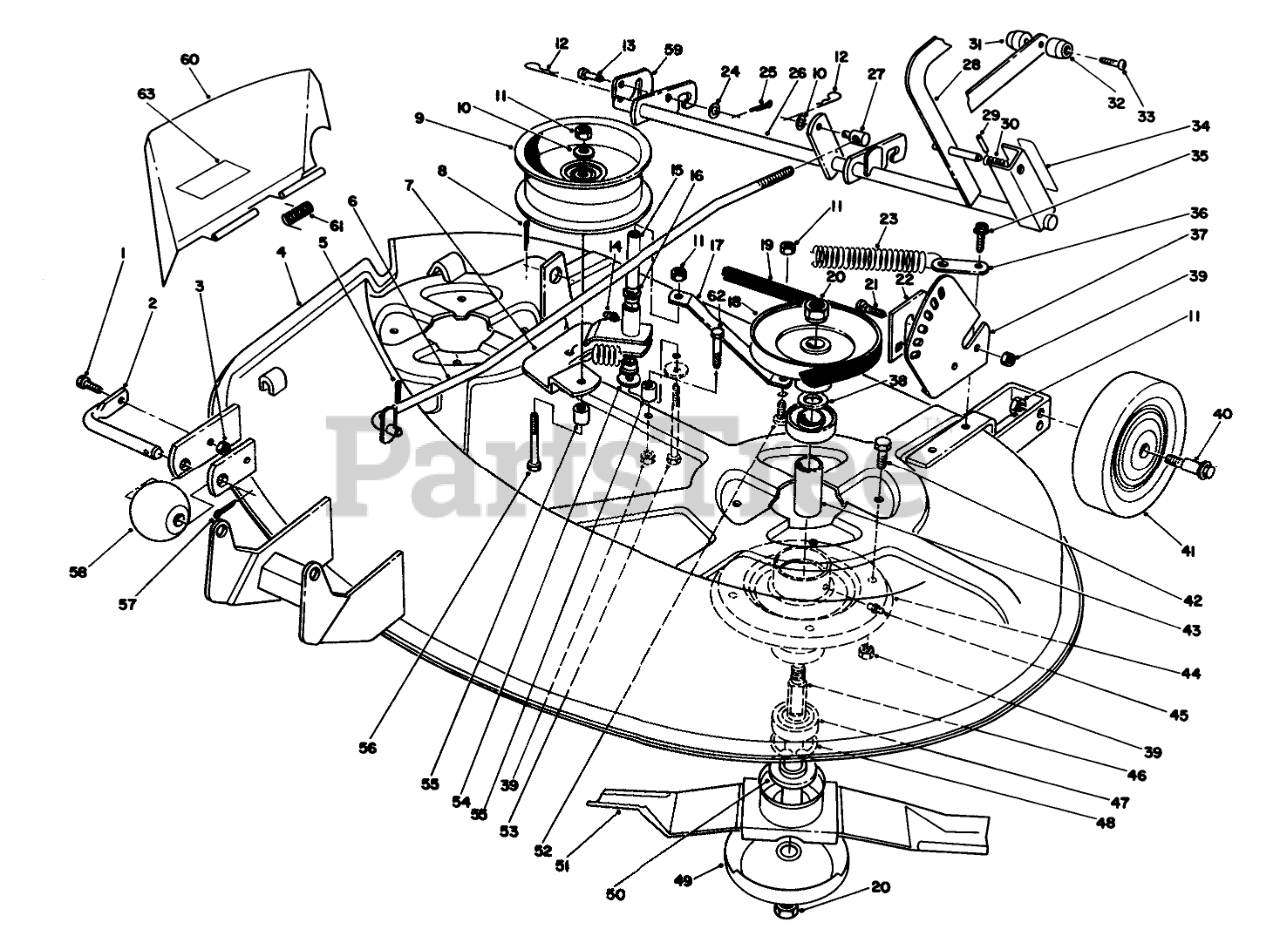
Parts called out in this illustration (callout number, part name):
1	Bolt
2	SHAFT-ROLLER
3	Nut
4	Deck W.A.
5	SPIROL PIN
6	WLDMT-HEIGHT ADJ R
7	WLDMT-IDLER ARM R
8	Pin-Cotter
9	PULLEY-IDLER
10	Washer
11	NUT
12	Hairpin Cotter
14	Grease Zerk
15	SPACER
16	BUSHING
17	BRACE R
18	PULLEY-SPINDLE
19	BELT-V
20	NUT-LOCK NI
21	Bolt
22	PLATE-RETAINING R
23	SPRING-EXTENSION
24	Washer
25	Cotter Pin
26	WLDMT-HEIGHT ADJ R
27	STUD-TRUNION
28	WLDMT-LIFT LEVER R
29	PIN-SPIROL
30	SPRING-COMPRESSION
31	KNOB
32	KNOB
33	BOLT-4
34	DECAL-HOC
35	Bolt
36	Lever
37	QUADRANT R
38	Washer
39	Nut
40	BOLT-WHEEL
41	WHEEL-DECK
42	Bolt
43	BEARING SPACER
44	Housing-Spindle
45	Fitting-Grease
46	W.A.-SPINDLE SHAFT
47	BEARING-BALL
48	RING-RETAINING
49	Cup
50	SPACER-SPINDLE
51	Blade
52	Bolt
53	Bolt 3/8-16 x 4
54	WASHER
55	SPACER
56	Bolt
57	Cotter Pin
58	ROLLER
59	LATCH B
60	Deflector
61	SPRING-TORSION
62	Bolt
63	DECAL-DANGER, THROWN OBJECT
